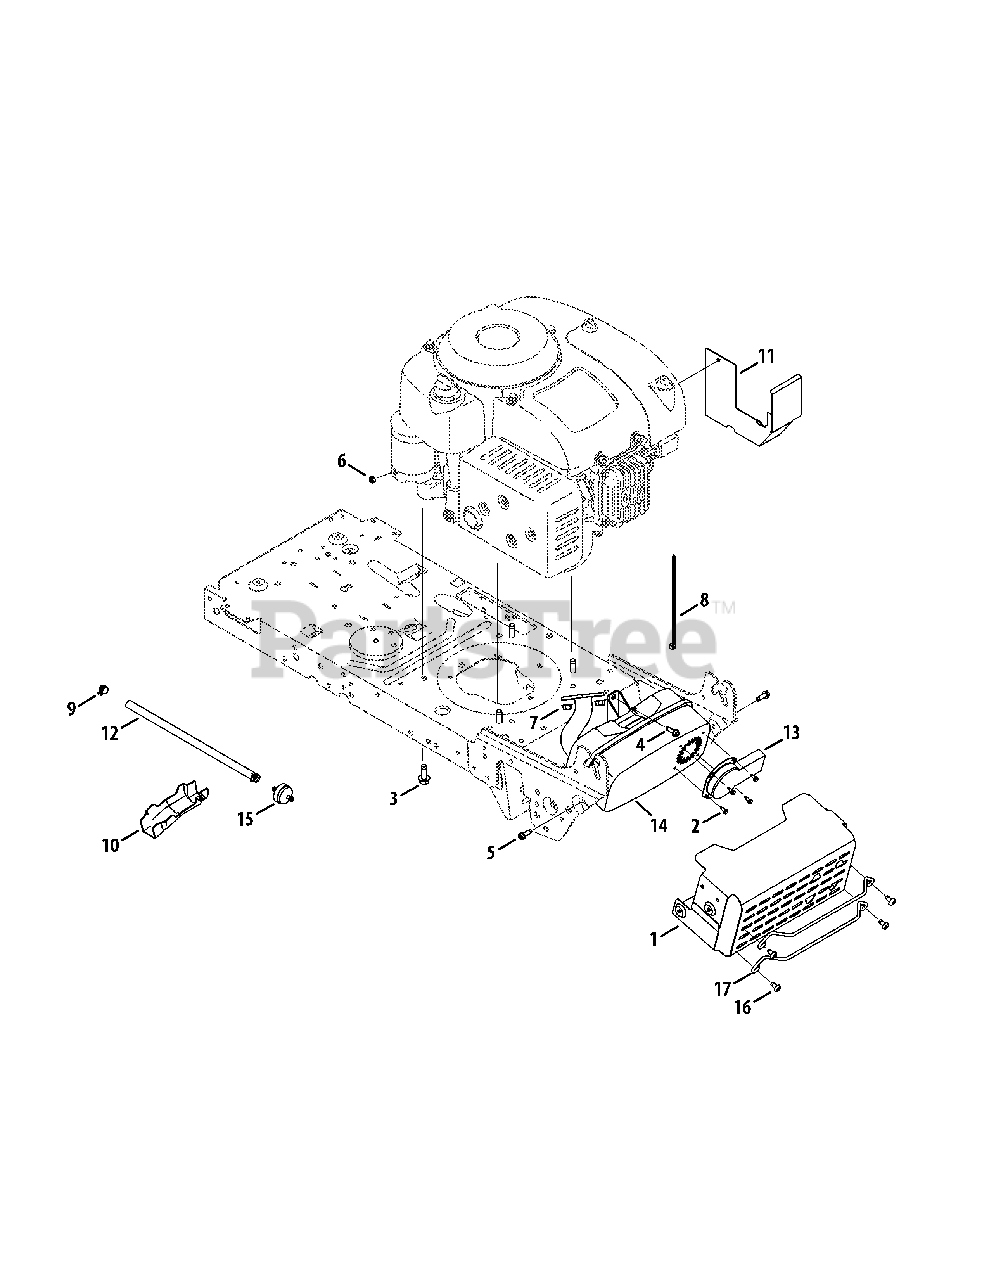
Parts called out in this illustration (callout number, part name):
1	Muffler Shield Assembly
2	Screw, 8-18 x .500
3	Screw, 3/8-16 x 1.0
4	Screw, 1/4-20 x .500
5	Screw, 1/4-20 x .750
6	Nut, M6-1, Hexlock
7	Flange Nut, M8-1.25
8	Cable Tie
9	Clamp Hose, .490 diameter
10	Oil Drain Sleeve
11	Deflector Bracket
12	Fuel Hose, Low Permeation
13	Muffler Deflector Long
14	Muffler
15	Fuel Filter
16	Pan Torx Screw 1/4
17	Muffler Guard Rod
